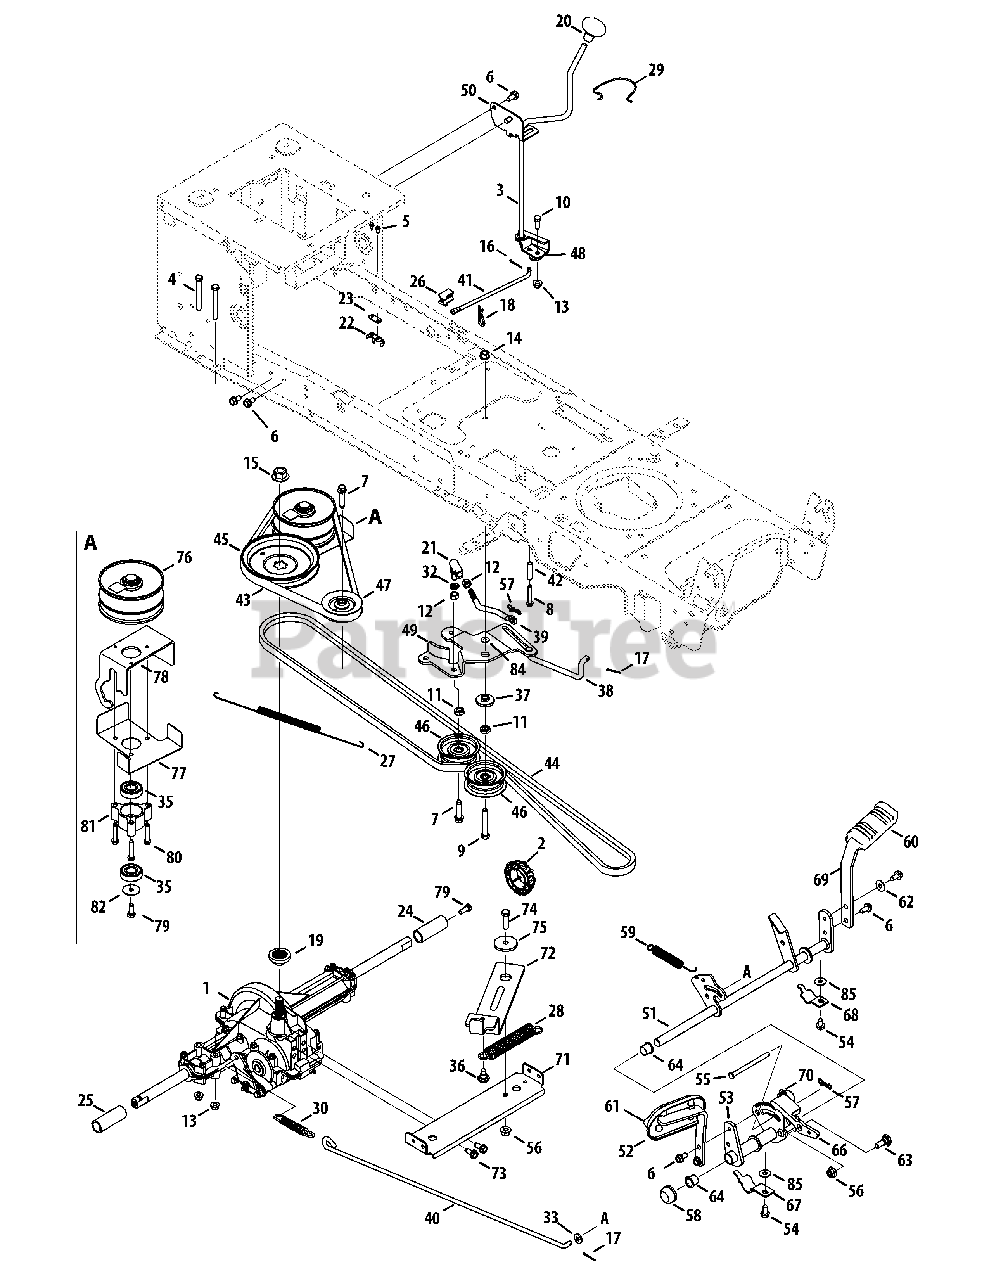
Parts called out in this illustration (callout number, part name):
1	Transaxle Ass’y
2	Hub Cap
3	Shift Lever Ass’y
4	Hex Scr 5/16-18 x 2.75
5	Hex Wash HD AB S-Tapp Scr #8-.50
6	Hex Wash Hd. Tapp Scr. 5/16-18 x .75
7	Hex L-Wash HD Scr 3/8-16 x 1.5
8	Hex TT-Tap Scr 1/4-20 x 1.75
9	Hex Bolt 3/8-16 x 2.25" Lg.
10	Screw-Hex Cap
11	Hex Jam Nut 7/16-20
12	Hex Nut 3/8-24
13	Flange Locknut 5/16-18 Gr. F, Ny lon
14	Hex. Flanged L-Nut 3/8-16 Gr. F
15	Flange Nut
16	Int. Cotter Pin .072 x 1.13" Lg.
17	Cotter Pin 3/32 dia x 1.00 Lg.
18	Cotter Pin
19	Hub 5/8" spline
20	Shift Knob
21	Drag Link Ball Joint
22	Short Spring Switch
23	Insulator Nut Plate
24	Sleeve .758 x .821 x 3.3125
25	Sleeve .758 x .821 x 2.4375
26	Shift Plate Bearing
27	Extension Spring .70 OD x 12.0
28	Extension Spring .97 OD x 6.18
29	Complete Spring Clip
30	Extension Spring .59 OD x 4.0
32	L-Wash 3/8 ID
33	Flat Washer .312 ID x .75 OD
35	Ball Bearing 17 x 40 x 12
36	Shoulder Screw 5/16-18, .43 x .29
37	Shoulder Spacer 1.375 x .380 x .183
38	Footpedal By pass Rod
39	Idler Adjustment Rod
40	Brake Rod
41	Shift Rod
42	Spacer .260 x .372 x 1.420
44	V-Belt
45	Pulley, V-Type, 7.25 dia.
46	Idler Pulley, Flat 2.75 OD
47	Idler Pulley V-Type x 3.06
48	Shift Adjustment Bracket
49	Idler Bracket (Centre Double)
50	Shift Bracket F-N-R
51	Brake Control Ass’y
52	AutoDrive Pedal Assembly
53	Pedal Bracket Assembly
54	Self-tapping Screw 5/16-18 x .625
55	Clevis Pin 5/16 x 3.985
56	Flange Lock-Nut 3/8-16 Gr. F Nylon
57	Bow-Tie Cotter Pin
58	Push Cap 5/8" Dia Rod
59	Extension Spring .63 dia. x 4.95
60	Brake Pedal Pad
61	AutoDrive Pedal Pad
62	Cupped Washer .345 ID x .88 OD x .060
63	Shoulder Screw .500 x .25
64	Nyliner Flanged Brg.
66	Cruise Latch
67	Pedal Strap Support Bracket
68	Pedal Strap Support Bracket
69	Brake Pedal Bracket
70	Reinforcement Plate Bracket
71	Transmission Bracket Assembly
72	Idler Bracket Ass’y
73	Hex Wash. Hd. Scr. 5/16-18 x .75 Lg.
74	Hex Bolt 3/8-16 x 1.25
75	Shoulder Spacer .884 x .190
76	Variable Speed Pulley Assembly 4.75 OD
77	Belt Keeper Ass’y
78	Variable Bracket Ass’y
79	Sems Scr. 5/16-24 x .75
80	Hex Wash HD Bolt 1/4-20 x 1.50" Lg.
81	Bearing Cup
82	Flat Washer .22 ID x 1.25
83	Flat Washer .350 x 1.59 x .062
84	Flat Washer .385 x 1.0 x .03
85	Flat Washer .344 x 0.688 x .065
